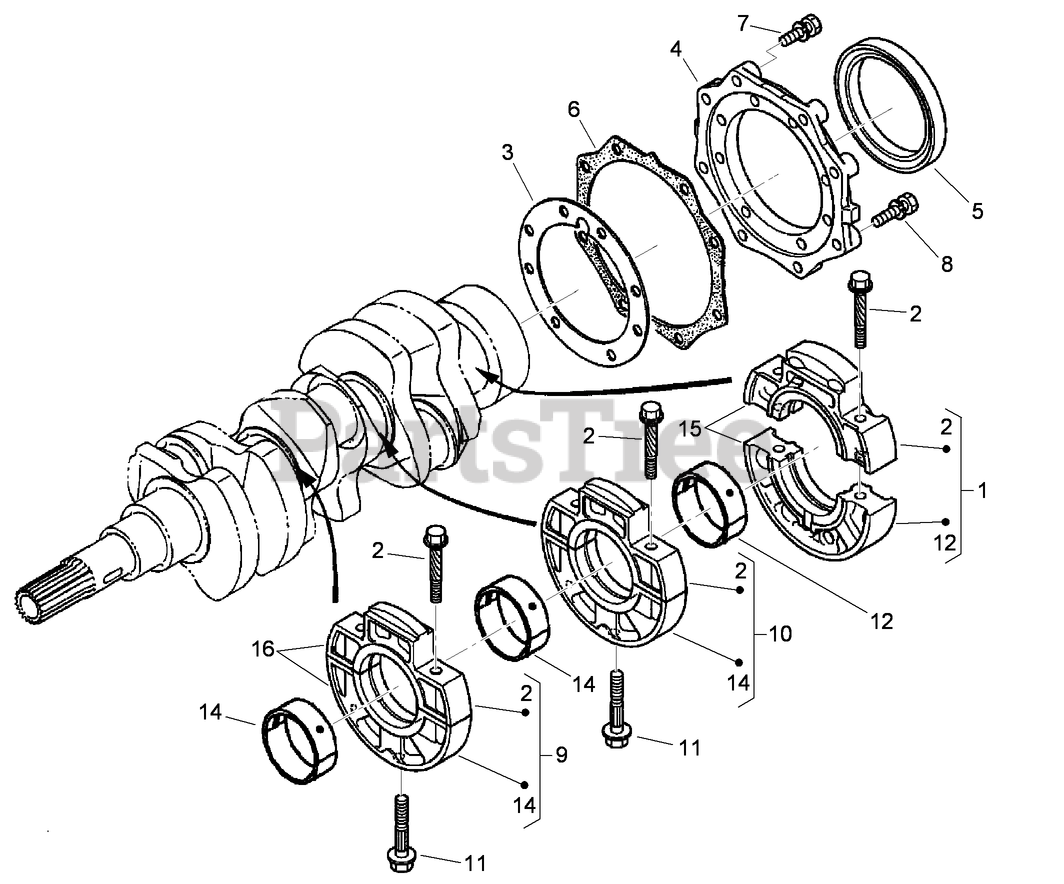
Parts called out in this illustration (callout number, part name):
2	BOLT-CASE, BEARING
3	GASKET-CASE, BEARING
4	COVER-CASE, BEARING
5	SEAL-OIL
6	GASKET-COVER, CASE
9	MAIN CASE BEARING ASM
10	MAIN CASE BEARING ASM
11	BOLT-CASE, BEARING
12	CRANKSHAFT METAL ASM (-0.20MM)
12	CRANKSHAFT METAL ASM (-0.40MM)
14	CRANKSHAFT METAL ASM (STD)
14	CRANKSHAFT METAL ASM (-0.20MM)
14	CRANKSHAFT METAL ASM (-0.40MM)
15	MAIN BEARING CASE ASM
16	MAIN BEARING CASE ASM
